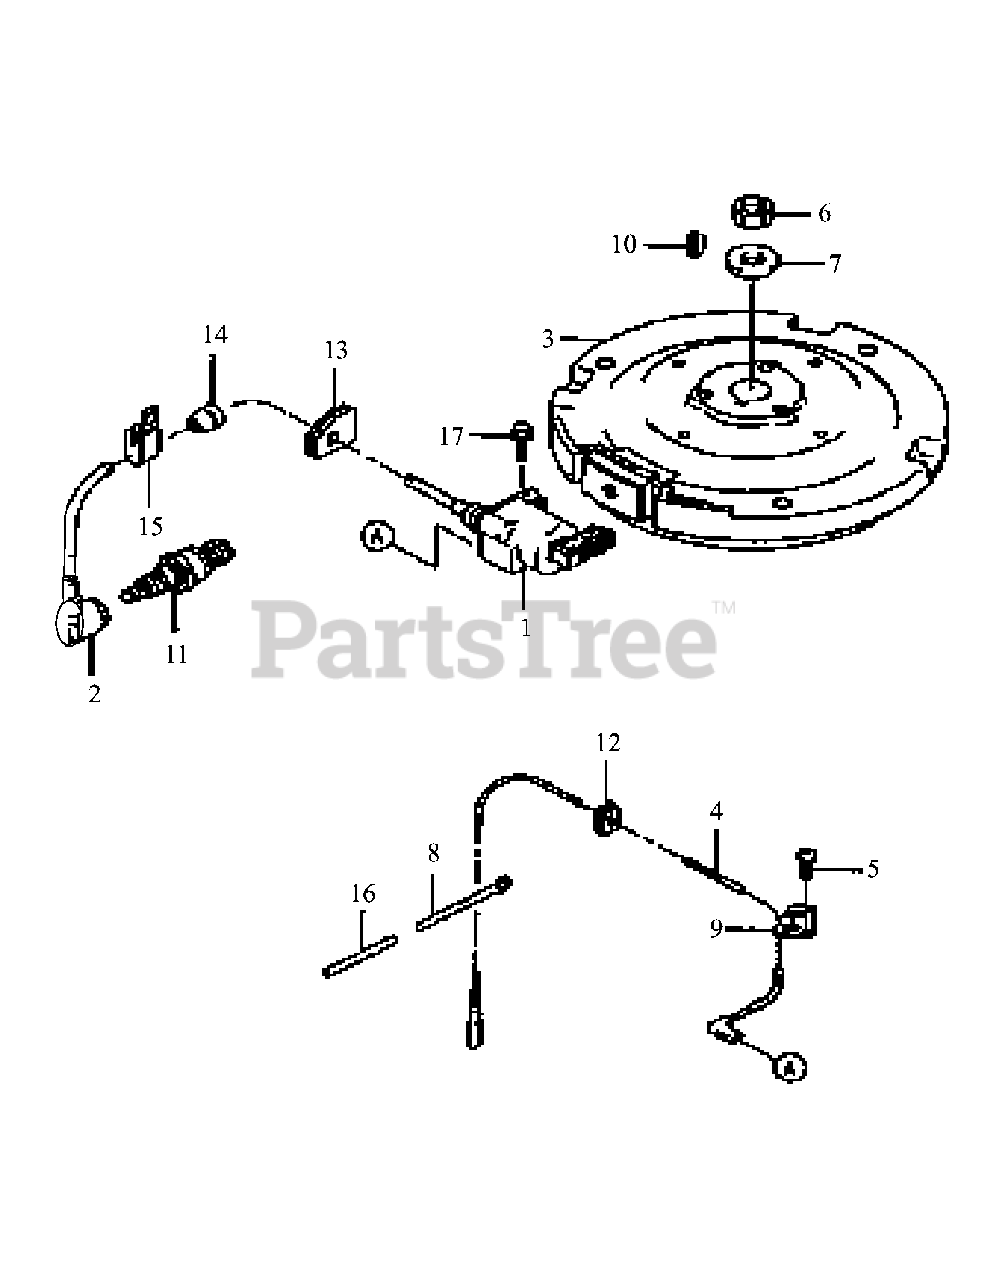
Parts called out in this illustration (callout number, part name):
1	Coil, Ignition
2	Cap, Spark Plug
4	Wire, Lead L=260
7	Washer
11	Spark Plug
17	Bolt, Flange
